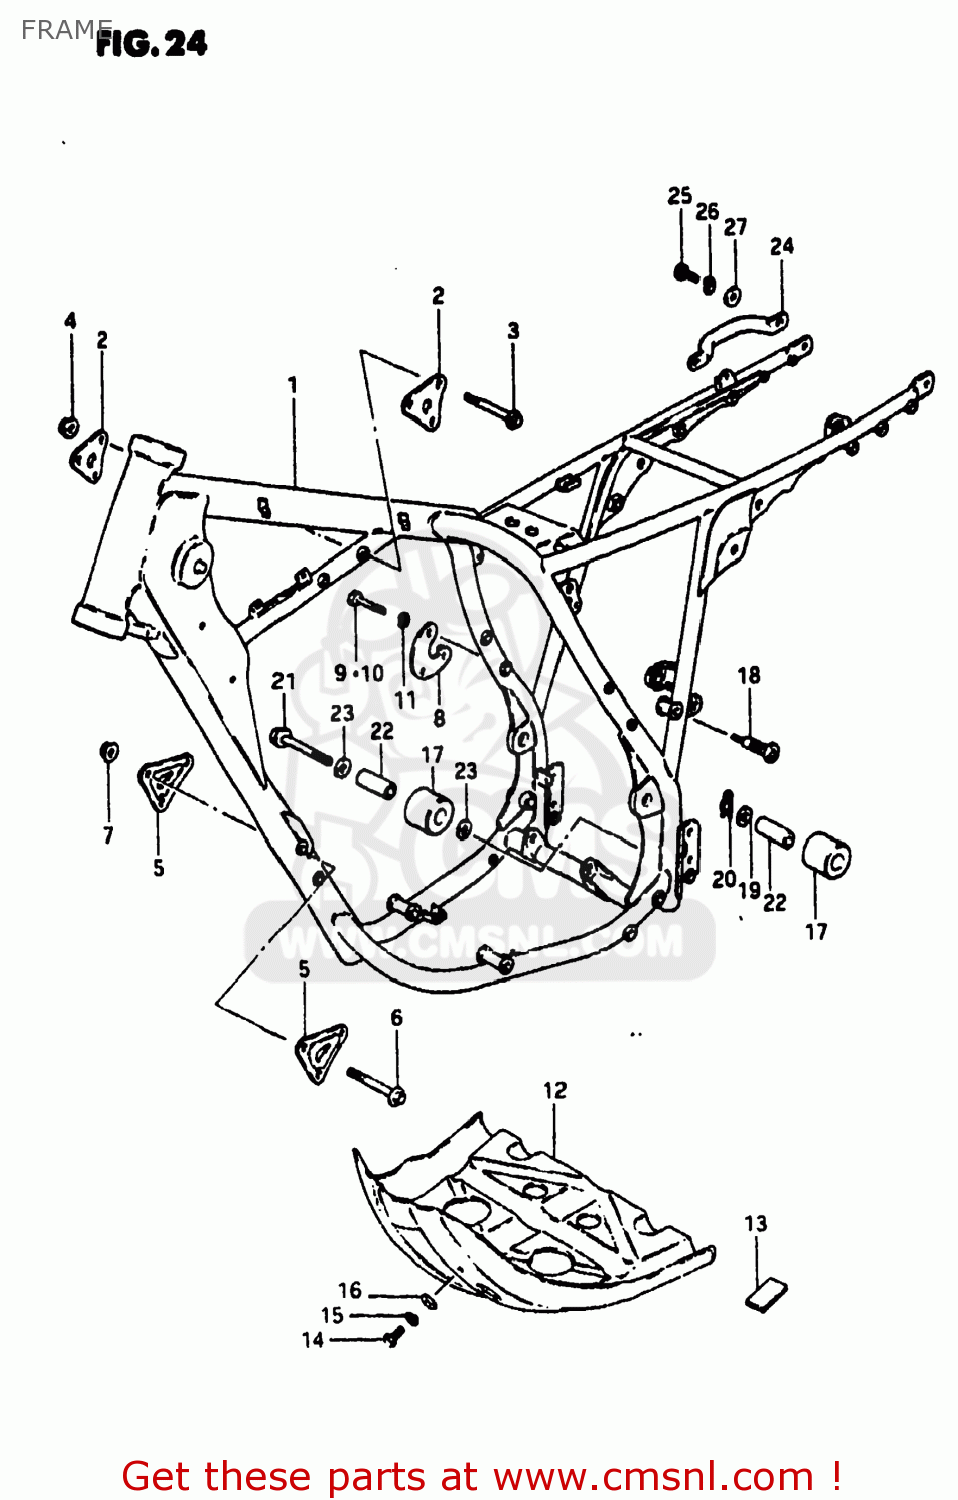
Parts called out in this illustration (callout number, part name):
1	FRAME
2	PLATE,ENGINE MOUNTING,UPPER
3	BOLT
4	NUT
5	PLATE,ENGINE MOUNTING,FRONT
6	BOLT
7	NUT
8	PLATE,ENGINE MOUNTING
9	BOLT
10	BOLT 8X50
11	LOCK WASHER
12	PLATE,ENGINE,UNDER
13	CUSHION,ENGINE,UNDER
14	BOLT
15	LOCK WASHER
16	WASHER
17	ROLLER,CHAIN LENGTH CONTROL
18	BOLT,CHAIN LENGTH ROLLER
19	WASHER
20	E RING 8MM
21	BOLT(8X45)
22	SPACER,CHAIN LENGTH ROLLER
23	WASHER
24	GRIP,FRAME HANDLE
25	BOLT
26	LOCK WASHER
27	WASHER
